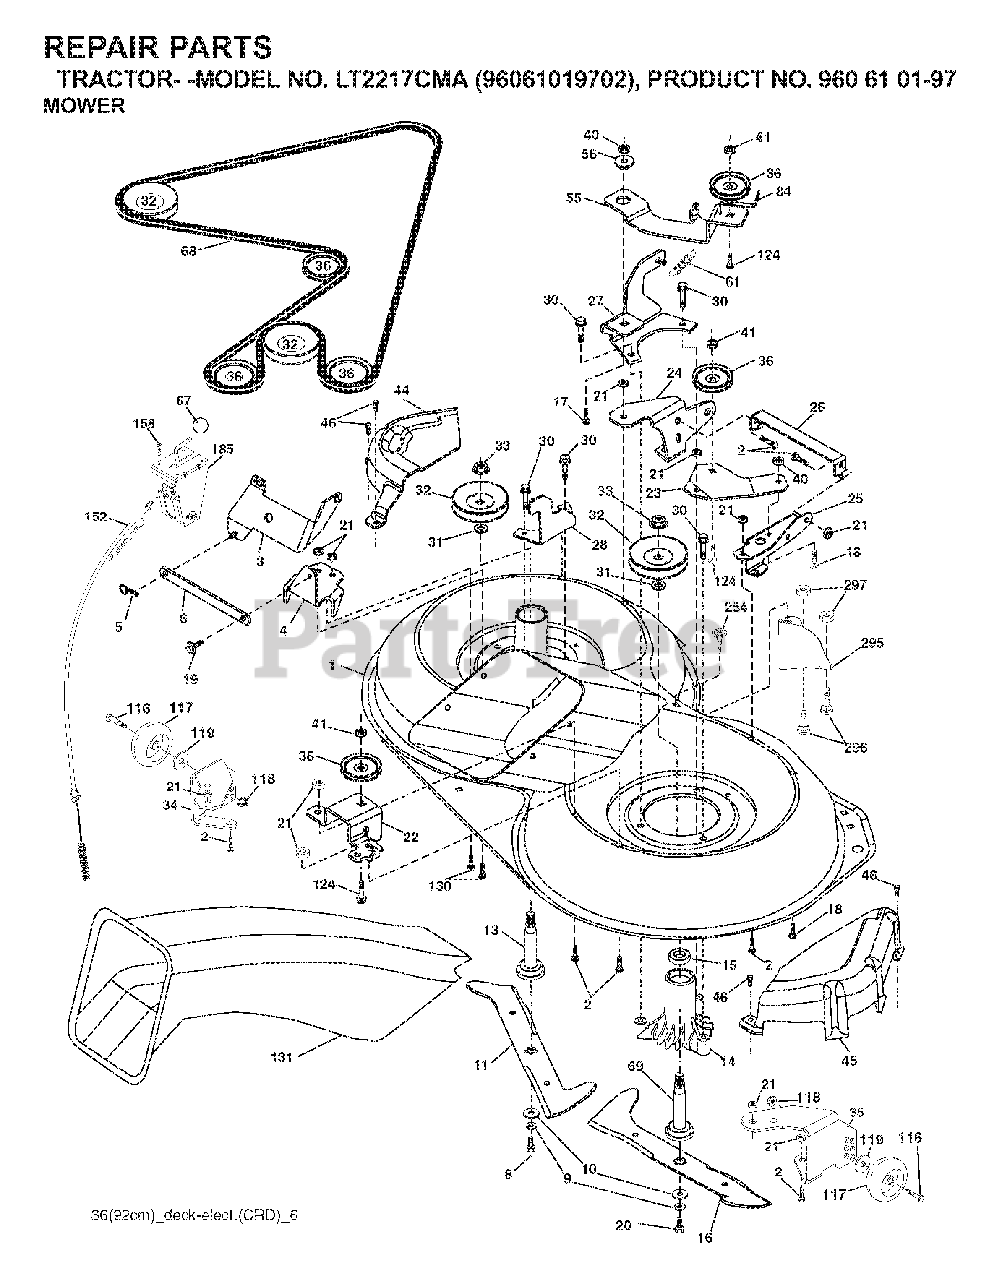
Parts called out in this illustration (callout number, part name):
2	BOLT
3	BRACKET
5	RETAINER-SPRNG RB
6	BAR SWAY
9	LOCKWASHER
10	WASHER.BLADE
13	SHAFT ASM VENT
14	HSG MANDREL
17	BOLT.3/8-14X1.25
19	BOLT SHD 5/16-18
21	LOCKNUT
24	BRACKET
25	BRACKET
28	BRACKET
30	SCREW, WASHER HEAD
31	WASHER.SPACER.MANDREL
32	PULLEY MANDREL
33	NUT.FLANGE.LOCK.TOP
36	PULLEY.IDLER.4.25
40	LOCKNUT
41	NUT LOCK FLG 3/8-16 UNC
45	MANDREL COVER
46	SCREW.1/4-20X5/8
56	SPACER.RETAINER.MOWER
67	KNOB T (3/8 HOLE)
69	SHAFT.ASM.W/LWR.BRG.RH.THREAD
84	KEEPER, BELT IDLER
116	BOLT.SHOULDER.3/8-16X3-5/8
117	WHEEL. GUAGE RALLY
118	NUT LOCK FLG 3/8-16 UNC
124	BOLT.3/8-16X1.50
131	CHUTE BAGGER
158	SCREW
185	HEAD ASM. CABLE CLUTCH
254	SCREW 3/8-16X1
296	BOLT
297	NUT CENTERLOCK
